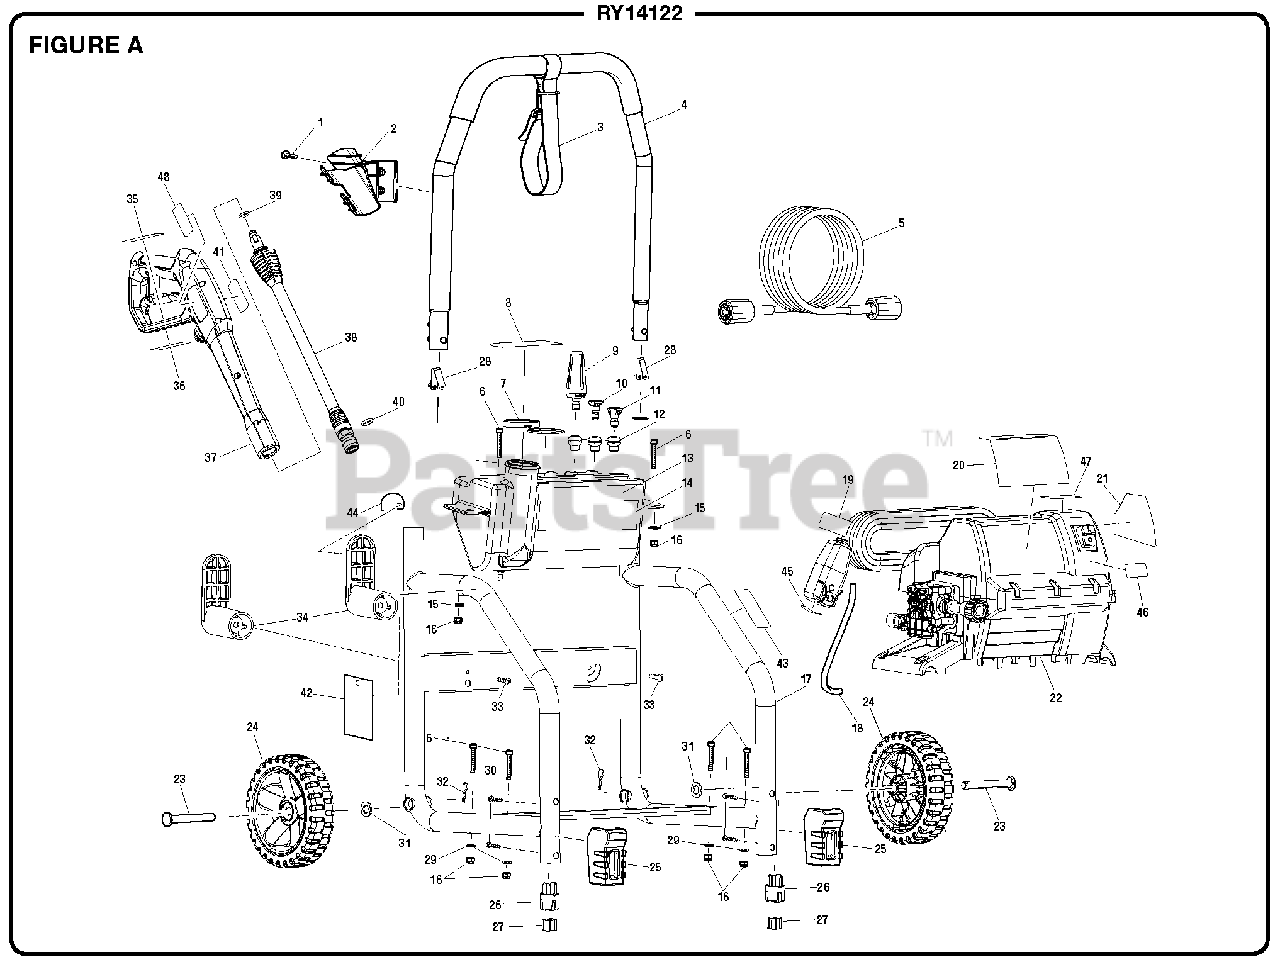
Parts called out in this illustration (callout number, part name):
1	Bolt (M6 x 20 mm)
2	Trigger Handle Holder
3	Hose Storage Strap
4	Handle Assembly
5	High Pressure Hose
6	Screw (M6 x 40 mm)
7	Detergent Tank Cap
8	Quick Start Label
9	Turbo Nozzle
10	Soap Nozzle
11	15deg Nozzle
12	Nozzle Grommet
13	Detergent Tank Assembly
14	Ryobi Logo Label
15	Washer (M6)
16	Lock Nut (M6)
17	Main Frame
18	Injection Hose
19	Cord Wrap Label
20	Performance Label
21	Danger Label
22	Pump Housing Assembly
23	Wheel Axle
25	Foot Cover
26	Foot
28	Spring Clip w/Button
29	Washer (M6)
30	Screw (M3.5 x 20 mm)
31	Washer (2 in.)
32	Hitch Pin
33	Screw (ST4.8 x 19 mm)
34	Cord Wrap Arm
35	Trigger Handle Warning Label (English)
36	Trigger Handle Warning Label (French/Spanish)
37	Trigger Handle
38	Spray Wand
39	O-Ring (Large)
40	O-Ring (Small)
41	Trigger Handle Rating Label
42	Warning Hangtag
43	Inquires Label
44	Cord Unlock Label
45	Cord Plug Label
46	On/Off Switch Label
47	Soap Dilution Label
48	Trigger Handle Label (Logo Label)
